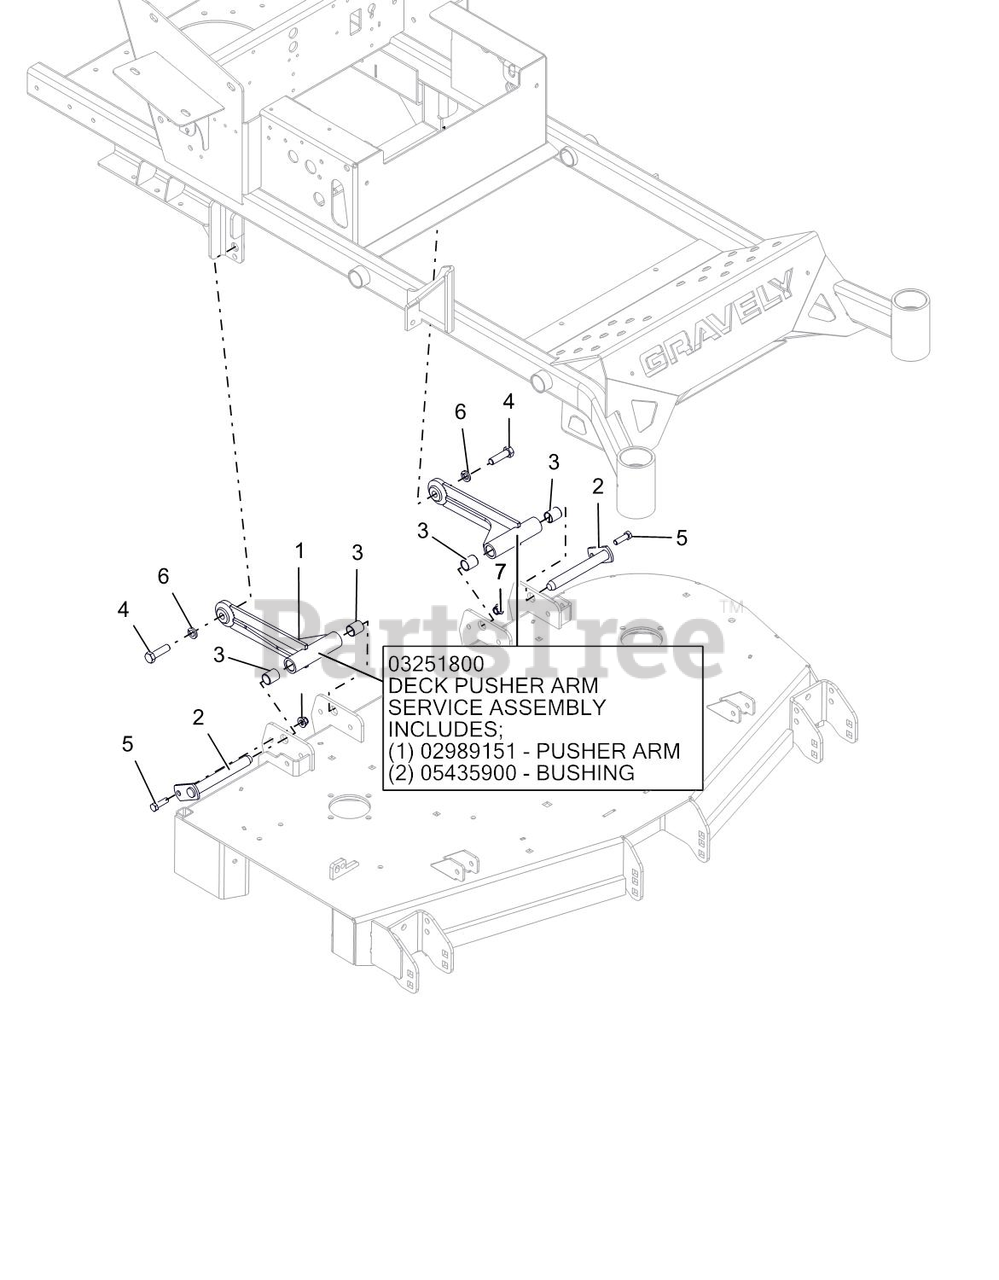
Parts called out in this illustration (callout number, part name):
1	DECK PUSHER ARM WLDMT - BLK
1	DECK PUSHER ARM SERVICE ASSEMBLY
1	PUSHER ARM
1	BUSHING
2	WLDMT, MOWER MTG. PIN
3	BRG, .750 X .875 X 1.000
4	BOLT, HEX 0.5-13X1.75 GR5
5	BOLT, HEX 0.375-16X1.25 GR5
6	WSHR-LK .50X.125 REG YWZC
7	NUT-LK-NYL-FLG .38-16 YWZC
